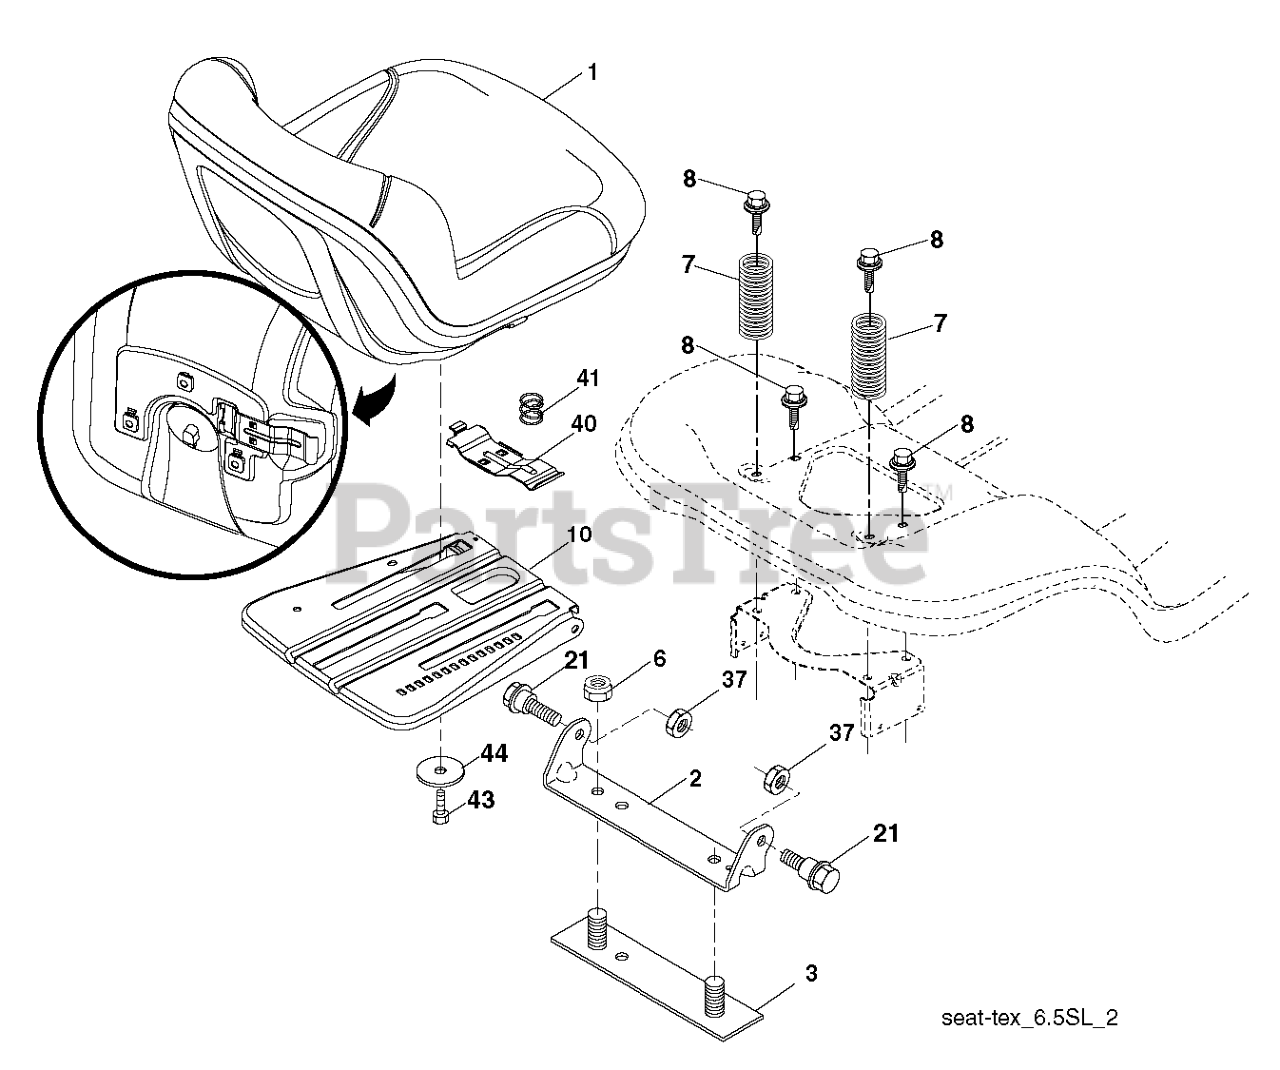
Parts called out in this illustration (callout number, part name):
1	SEAT.TH150.MS498.GRY.HUSQ.TEX
2	BRKT.PIVOT.FENDER
3	STRAP
6	NUT
7	SPRING COMPRESSION
8	BOLT.5/16-18UNCX3/4 W/SEMS.BLK
10	PAN.ASM.SEAT.3PT
21	BOLT.SHOULDER.5/16-18
37	NUT.71038.31-18.HEX.NYLOCK
40	HANDLE.SLIDE.SEAT.TEX.BLACK
41	SPRING.LATCH.SEAT.TEX
44	WASHER 13/32 X 2-3/8 X 12GA
